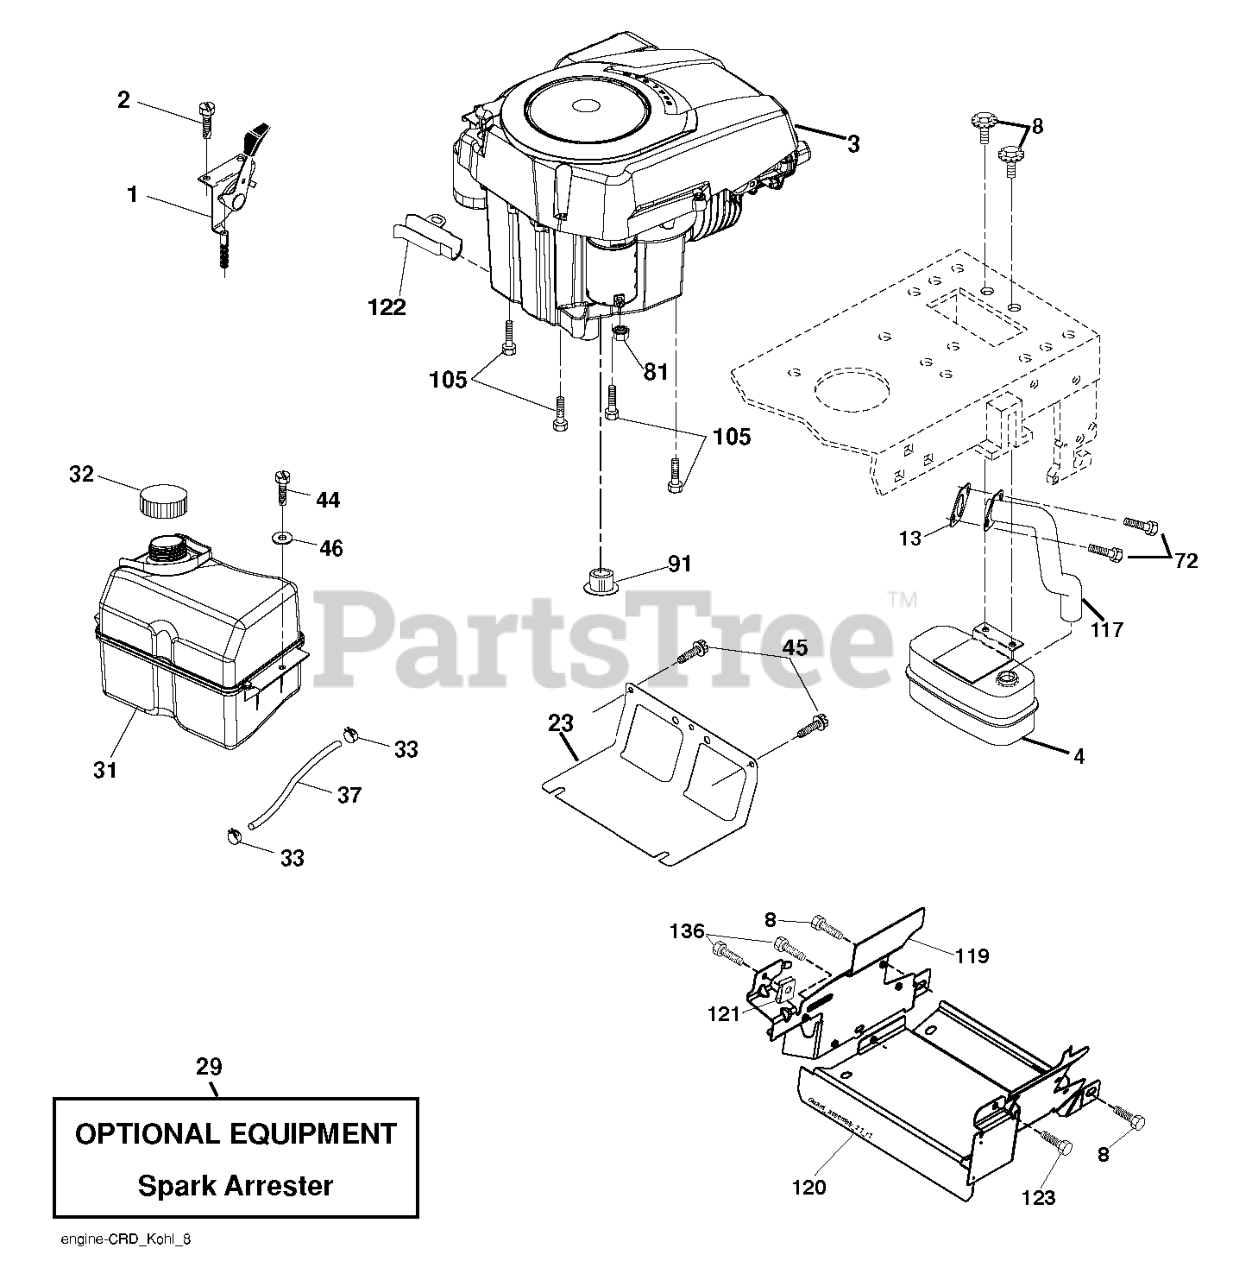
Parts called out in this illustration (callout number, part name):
1	CONTROL.TH/CK.C.
2	SCREW.#10 X 0.750.BOS
4	MUFFLER.SINGLE.CYL.KOHL/B&S
8	BOLT.5/16-18UNCX3/4 W/SEMS.BLK
13	GASKET.EXHAUST.KOHLER
23	SHIELD.BROWNING.DBR.GUARD
29	KIT.SPARK ARRESTOR 794945 B&S
31	RP TANK FUEL FRT 1.5 GAL
32	CAP ASM.FUEL.2.25"FR.
33	HOSE CLAMP
37	LINE.FUEL.20
44	SCREW HEXWSHR 1/4-20X3/4
45	SCREW, 3/8-16X3/4
72	SCREW.SOCKET HD.5/16-1
81	NUT
91	BUSHING.1.375OD
105	SCREW 3/8-16X1
117	RP.TUBE.EXHAUST.KOHL.COURAGE
119	LENKRAD
120	GUARD 532199767
122	EXTENSION DRAIN OIL
123	SCREW, 5/16-18 X 1/2
136	SCREW.1/4-20X5/8
